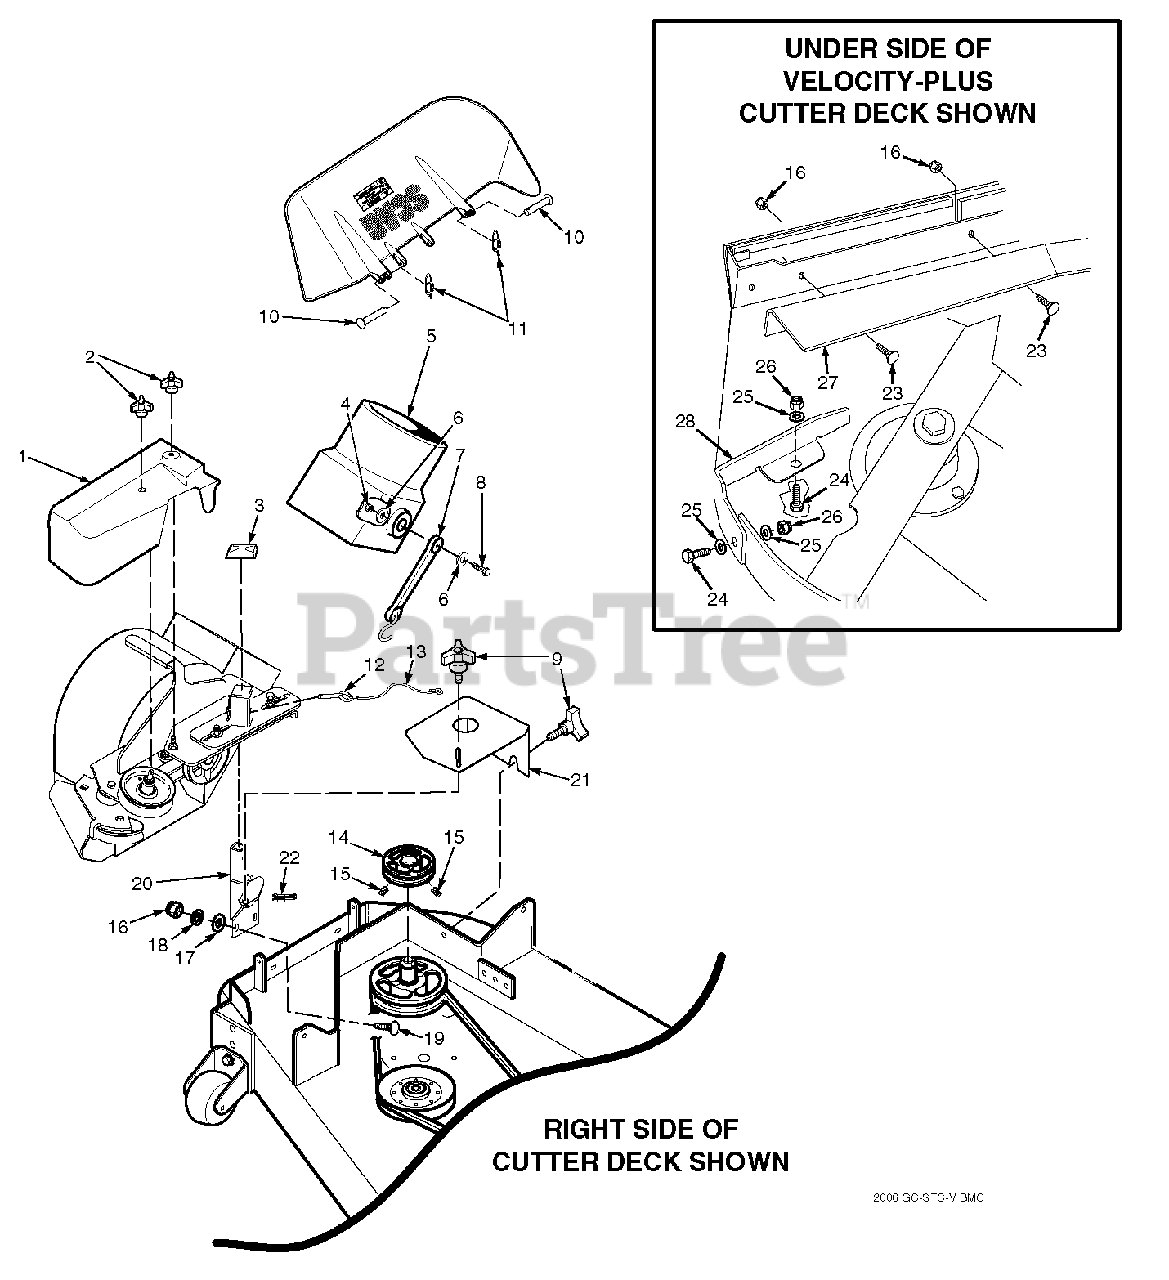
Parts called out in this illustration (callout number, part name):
1	Belt Cover, GC-STT - 61"
2	Wingnut, Plastic 3/8" Small
3	Cap, Square Vinyl
4	Nut, Elastic Stop 1/4-20
5	Adapter, Blower GC-STT
6	Flatwasher, 1/4-.312 x .750 x .065
7	Rubber Strap 7-3/4"
8	Bolt, Hex Head 1/4-20 x 1-1/4"
9	Knob W/Stud, 3/8-16 x 1-1/4"
10	Clevis Pin, 5/16 x 1-1/2"
11	Pin, Rue Cotter 5/16 Dia.
12	Pin, Ring 1/2 x 2-1/4"
13	Lanyard
14	Pulley, 5-1/2" Dia. - 1.125" Bore
15	Setscrew, 5/16-18 x 3/8"
16	Nut, Elastic Stop 3/8-16
17	Lockwasher, 3/8"
18	Flatwasher, 3/8-.391 x .938 x .105
19	Bolt, Carr. 3/8-16 x 1-1/4" Grade 5
20	Mounting Post Weldment, Blower
21	Belt Cover Assembly, GC-STT-61V w/Cap
23	Bolt, Carriage 3/8-16 x 1"
24	Bolt, Hex Head 5/16-18 x 1"
25	Flatwasher, 5/16-.375 x .875 x .083
26	Nut, Elastic Stop 5/16-18
27	Baffle, Front
28	Baffle, Turbo
